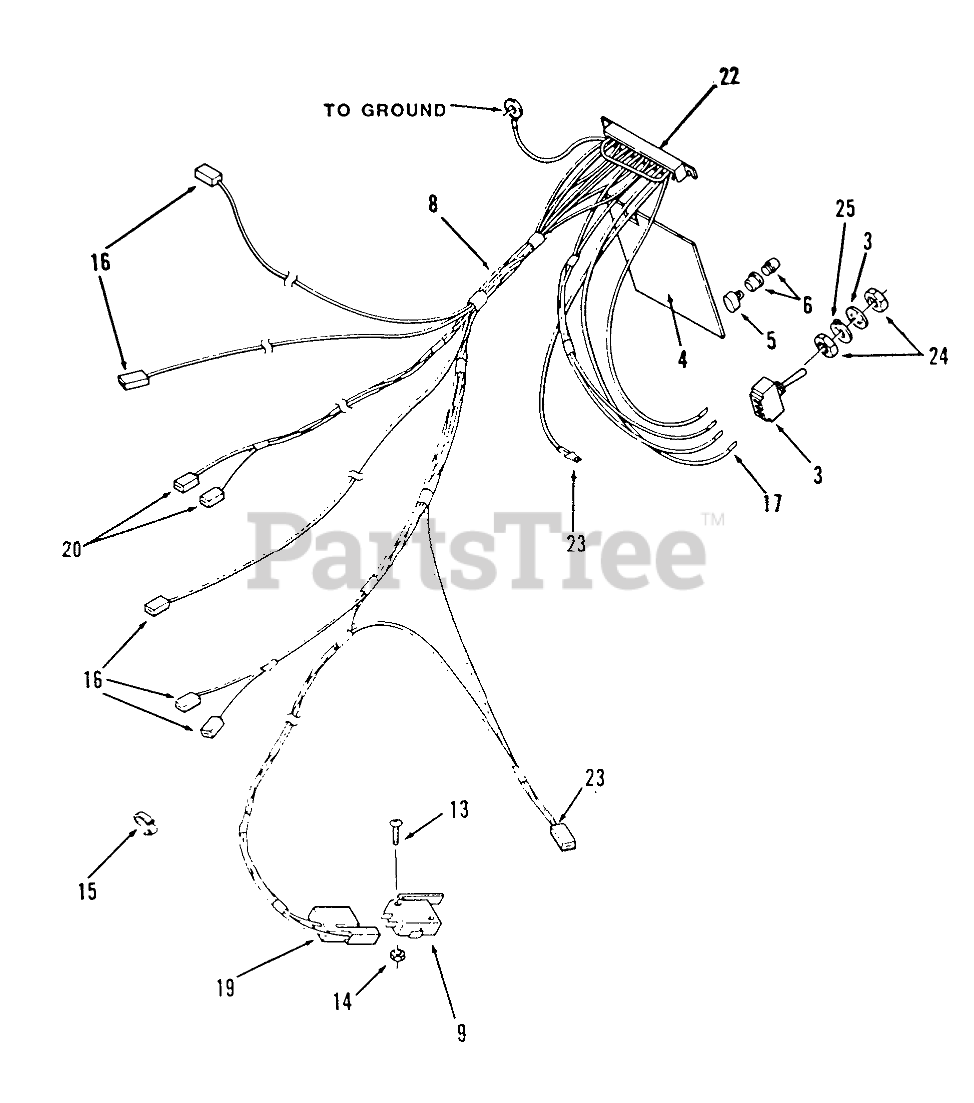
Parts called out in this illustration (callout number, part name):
3	SWITCH TOGGLE
4	Board-Pc
5	LIGHT INDICATOR
6	ASSY LENS & BUSHING
8	WIRING HARNESS
9	SWITCH
13	Screw
14	NUT HEX 4-40 ELAST
15	CLIP-CABLE
16	Piggy-Back Connector (Part of 6)
17	062 X 031 TAB RECEPT
19	CONNECTOR BODY
20	Piggy-Back Connector(Part of 6)
22	Molex Connector (Part of 6)
23	TERMINAL-LONG MALE
24	NUT F/W 116796
25	RING LOCKING
